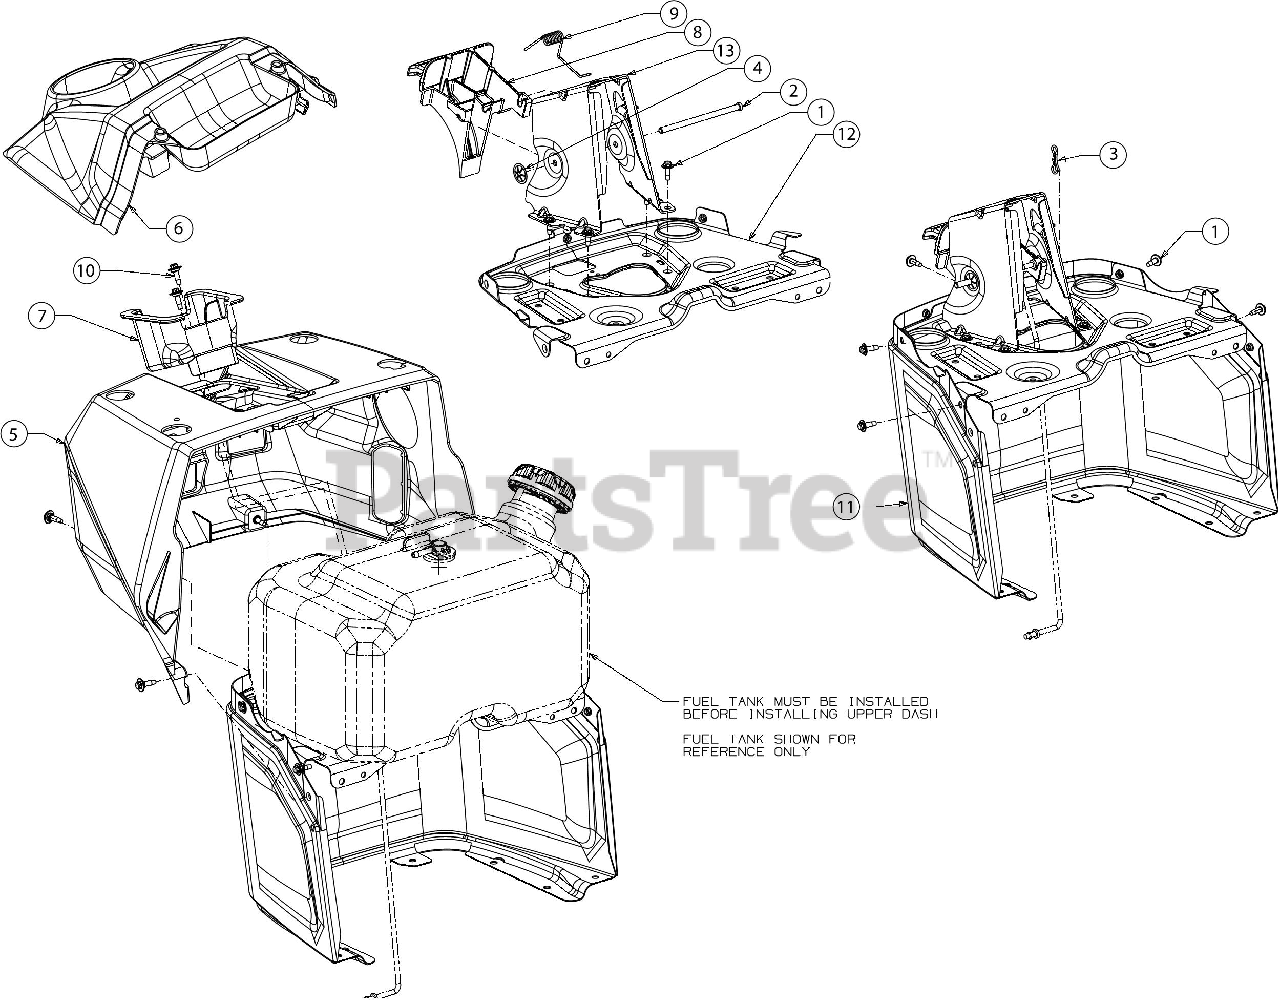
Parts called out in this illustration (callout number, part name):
1	SCREW M6-1 X .625
2	HINGE PIN .25 X 4.50
3	BOW TIE COTTER PIN 1/4-5/16
4	PUSH ON NUT
5	UPPER DASH
6	UPPER DASH CAP
7	STEERING SHAFT BEARING
8	CRUISE/BRAKE DASH LEVER
9	TORSION SPRING
10	SHOULDER SCREW M6-1 .368 X.115
11	LOWER DASH
12	DASH/FUEL TANK PLATE
13	STEERING MOUNT BRACKET
